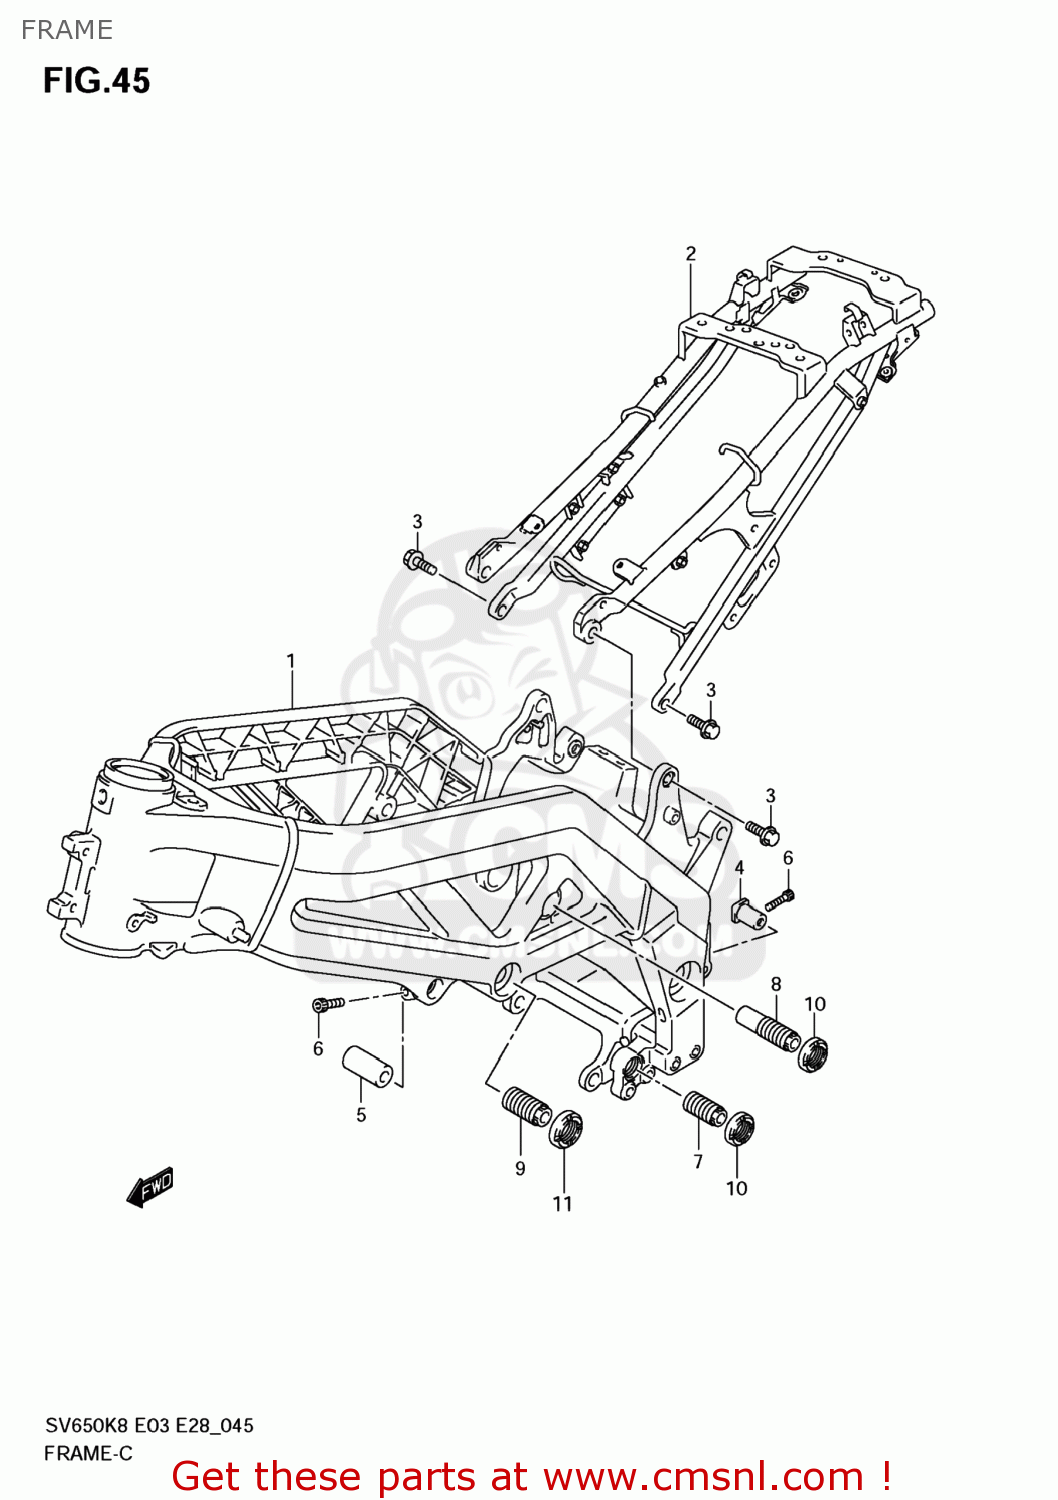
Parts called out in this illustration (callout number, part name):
1	FRAME(BLACK)
2	RAIL,SEAT(BLACK)
3	BOLT,SEAT RAIL
4	SPACER,MOUNTING RR UPR,R
5	SPACER,ENG HEAD MTG RR,L
6	BOLT(8X32)
7	BOLT,CASE LWR & RR HEAD ADJ
8	BOLT,ENGINE MOUNTING RR,L
9	BOLT,CRANK CASE ADJUST CTR
10	NUT,CRANK CASE ADJUST BOLT
11	NUT,CRANKCASE ADJUST
